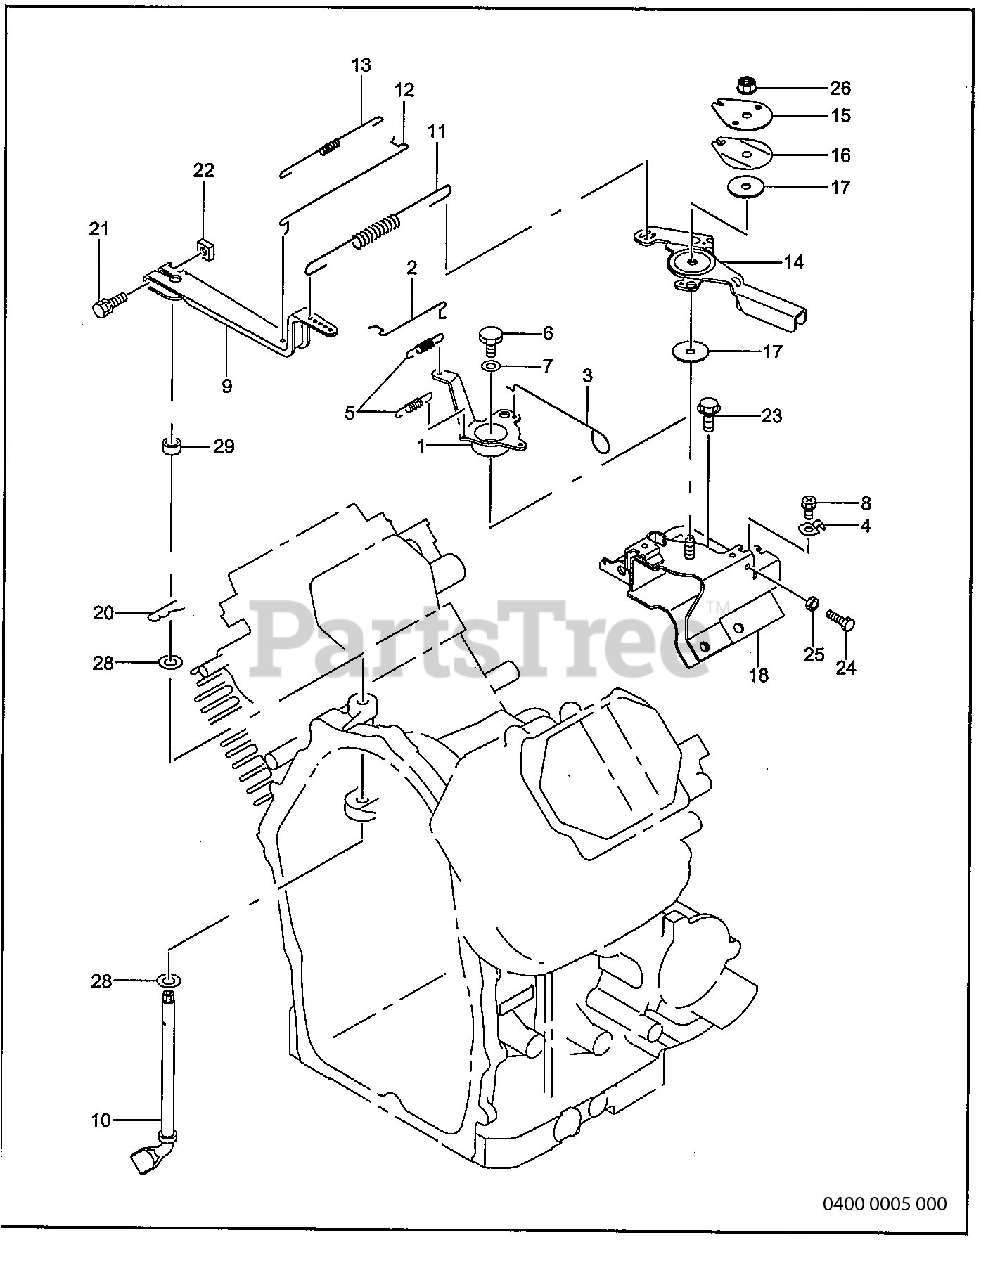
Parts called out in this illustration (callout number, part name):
1	CHOKE CONTROL LINK
2	CHOKE CONTROL ROD
4	CLAMP, choke knob
9	GOVERNOR LEVER
10	GOVERNOR SHAFT
11	GOVERNOR SPRING
14	SPEED CONTROL LEVER
17	FRICTION WASHER
18	BRACKET UNIT, speed control
21	BOLT and WASHER ASSY
